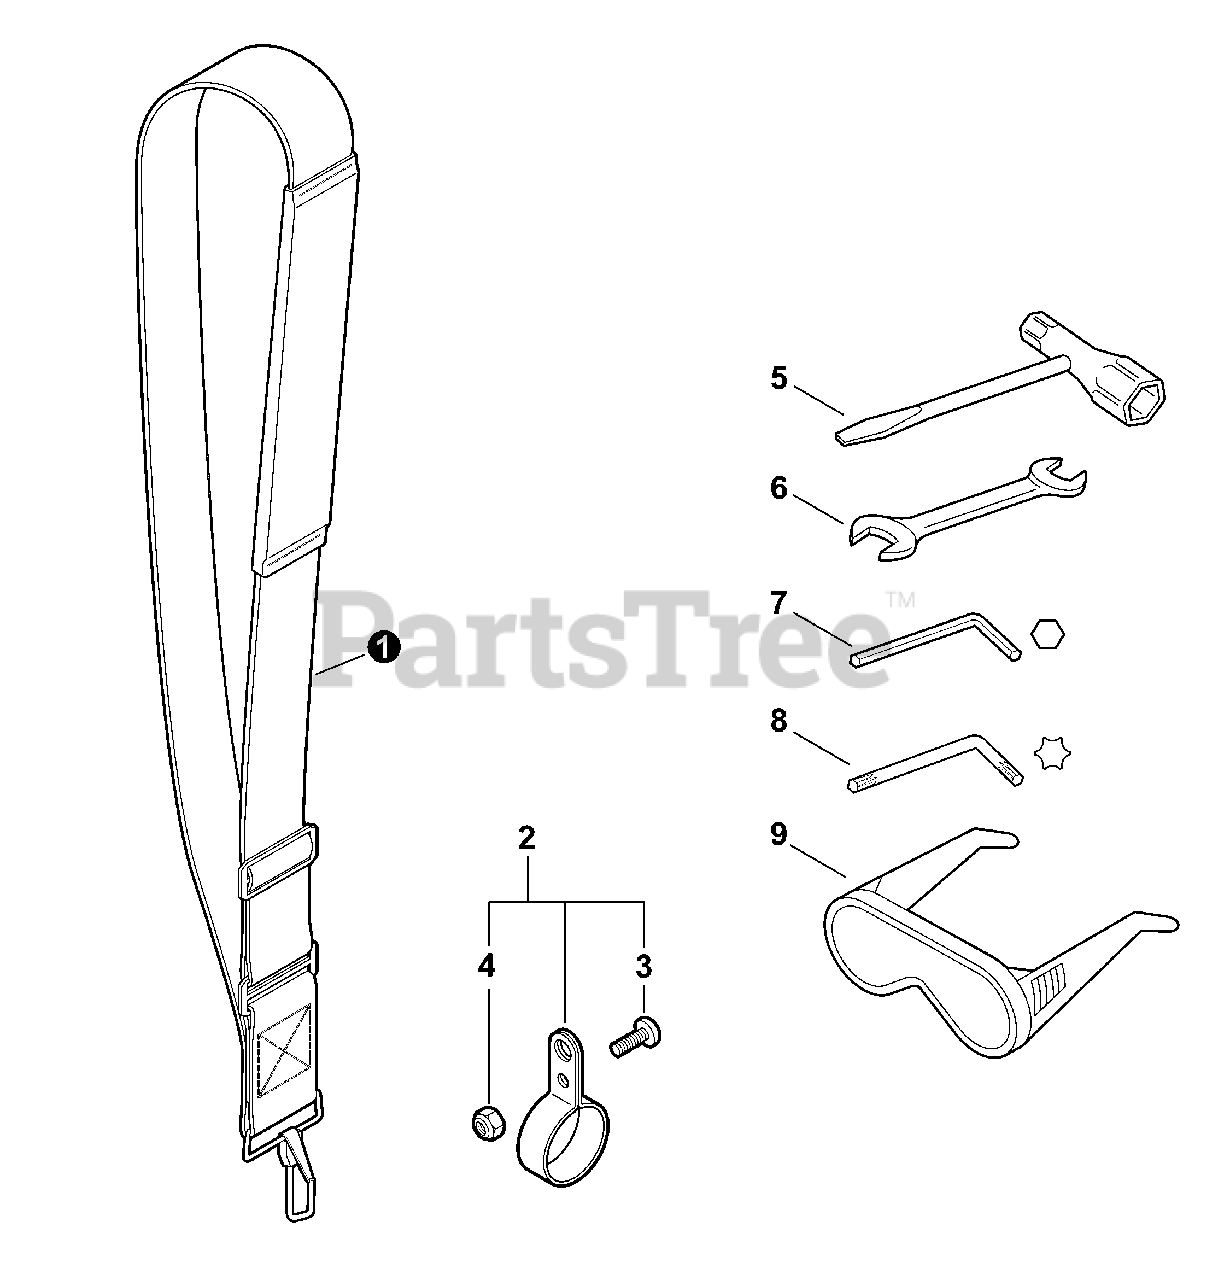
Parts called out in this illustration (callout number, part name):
1	SHOULDER STRAP ASY
2	HANGER KIT
3	SCREW - TORX PAN HEAD
4	LOCKNUT
5	T-WRENCH - 10×19mm
6	SPANNER - 8×10mm
7	KEY - HEX -- 4mm
8	TOOL, L WRENCH
9	GOGGLES
